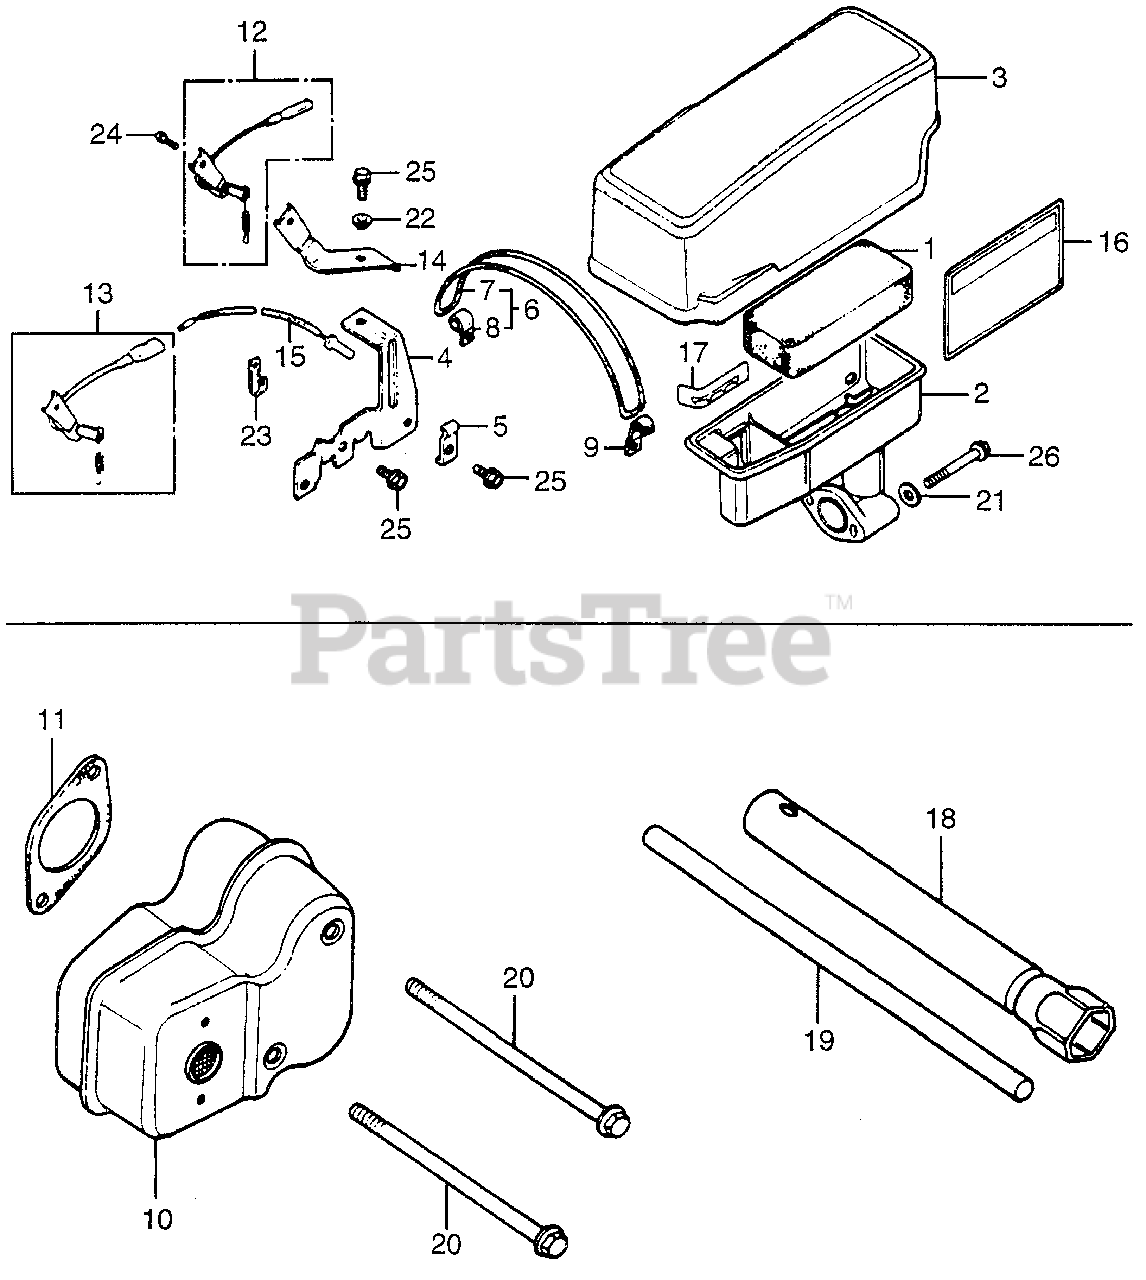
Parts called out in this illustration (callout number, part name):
1	ELEMENT, AIR CLEANER (NOT AVAILABLE)
2	HOUSING, AIR CLEANER *NH1L* (BLACK)
3	COVER, AIR CLEANER *NH1* (BLACK)
4	STAY, CLEANER CASE
5	HOLDER, CABLE
6	BAND, AIR CLEANER
7	BAND, AIR CLEANER
8	BAND, AIR CLEANER
9	HOLDER, AIR CLEANER BAND
10	MUFFLER
11	GASKET, MUFFLER
12	SWITCH ASSY., ENGINE
13	SWITCH, ENGINE
14	STAY, STOP SWITCH
15	WIRE, ENGINE SWITCH
17	MARK, CONTROL (NOT AVAILABLE)
18	WRENCH, SPARK PLUG
19	HANDLE, BOX WRENCH (NOT AVAILABLE)
20	BOLT, FLANGE (6X95)
21	WASHER (6MM)
22	WASHER, HEADLIGHT CASE
23	CLIP, WIRE HARNESS (NOT AVAILABLE)
24	SCREW, PAN (3X6)
25	BOLT, FLANGE (6X12)
26	BOLT, FLANGE (6X40)
26	BOLT, FLANGE (6X50)
